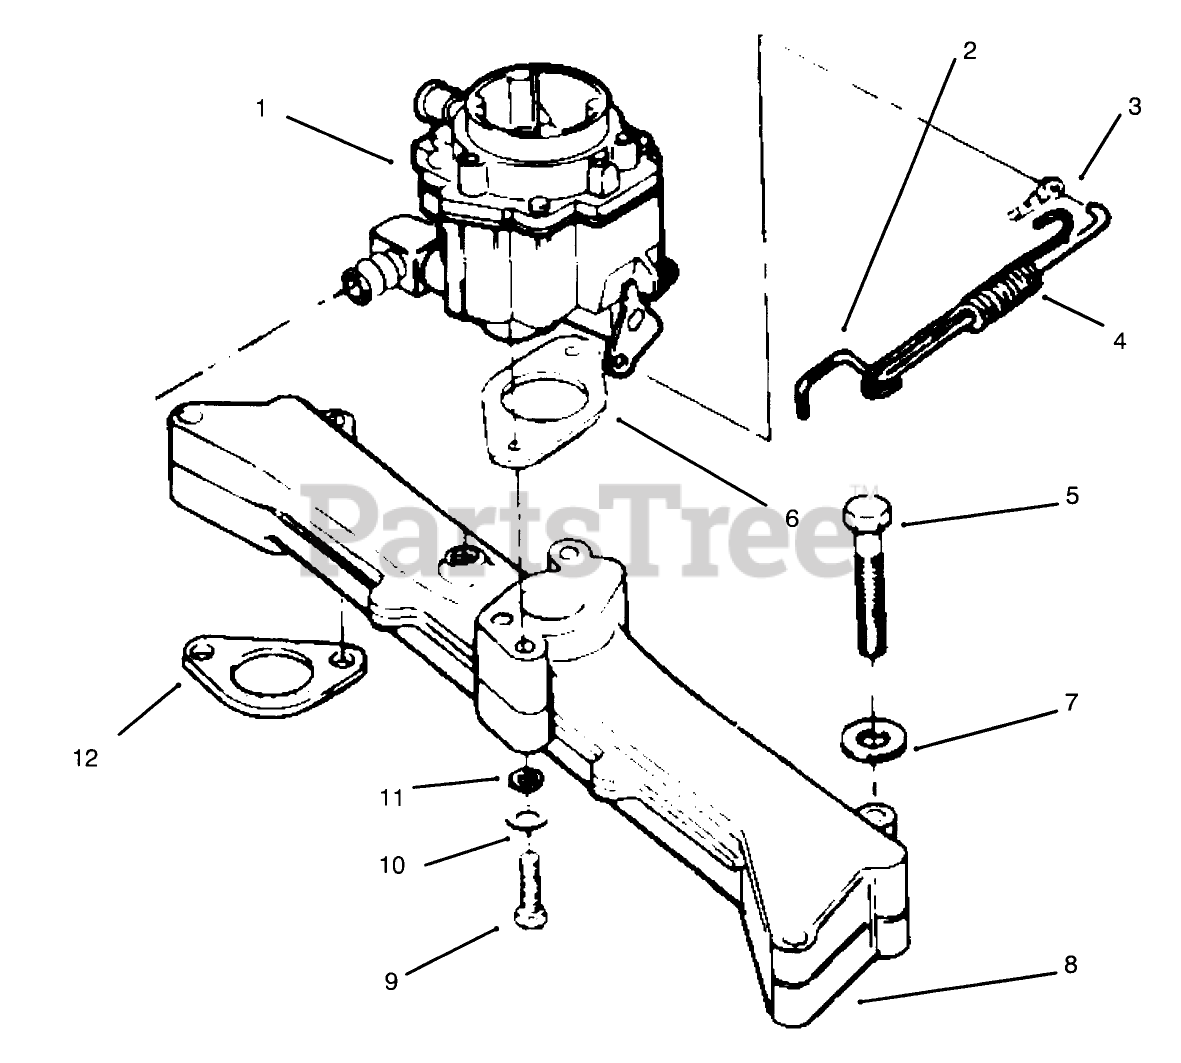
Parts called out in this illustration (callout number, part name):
1	Kit-Carburetor Low Emission NOT REPAIRABLE
2	ROD-GOV CONTROL
4	Spring-Governor Rod
5	SCREW-HH
6	GASKET-CARBURETOR
7	WASHER-FLAT
8	MANIFOLD - INTAKE
9	HEX HD CAP SCR
10	WASHER-FLAT
11	WASHER-FLAT
12	GASKET-MANIFOLD TO BLOCK
